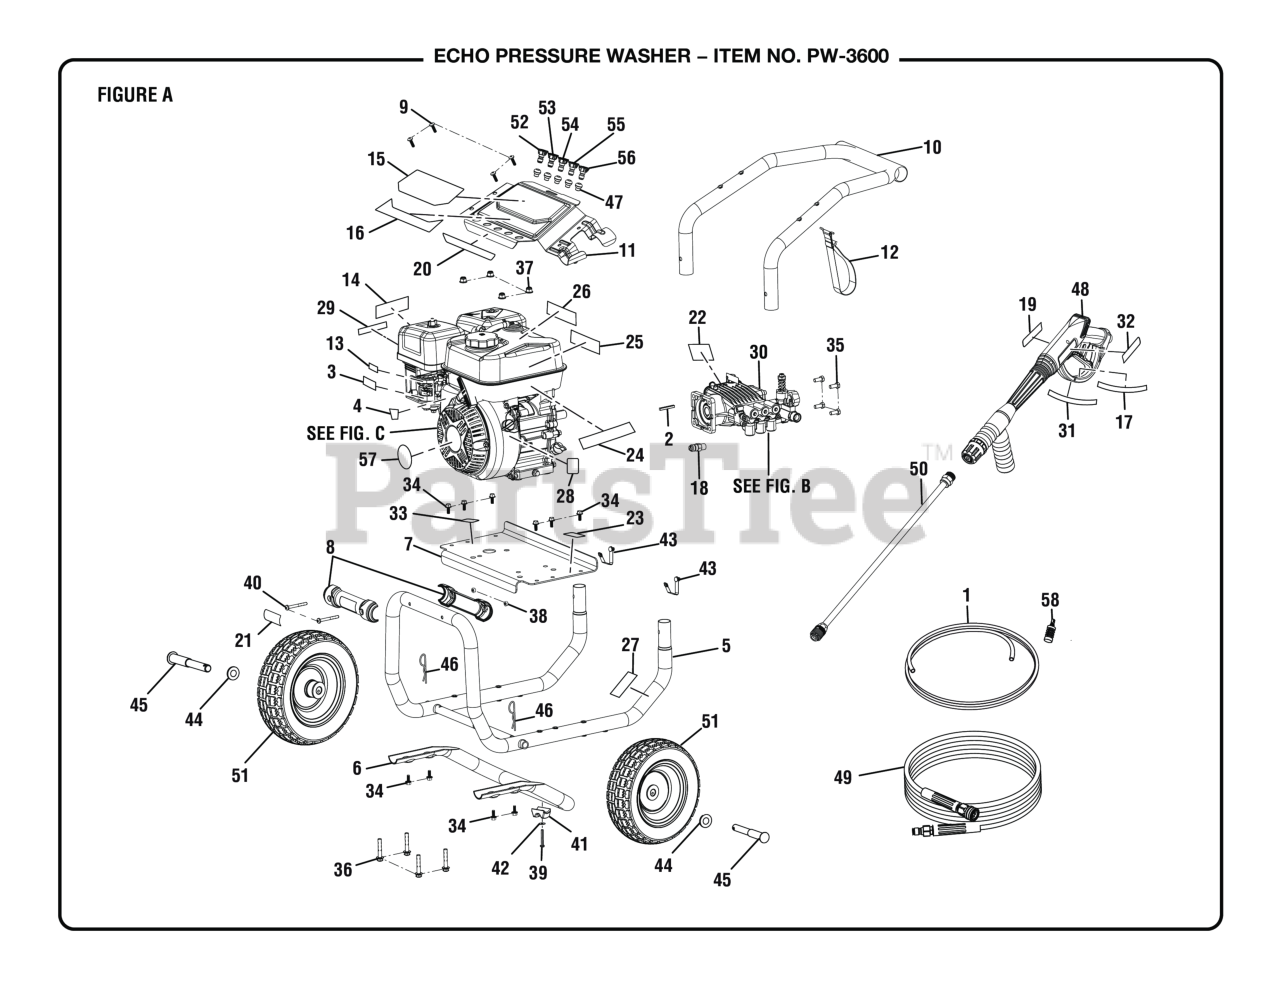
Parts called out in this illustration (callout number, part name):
1	HOSE, SIPHON
3	LABEL, FUEL VALVE
4	LABEL, CHOKE/FUEL CALLOUT
5	FRAME, MAIN
6	FRAME, REAR
7	PLATE, ENGINE
8	GRIP, FRONT HANDLE
9	SCREW, PHILLIPS HEAD
10	FRAME, HANDLE
12	PLATE, CHAIN GUARD
13	LABEL, CHOKE
14	LABEL, HOT SURFACE
15	LABEL, LOGO
16	LABEL, PERFORMANCE
17	LABEL, TRIG HNDL(FR/SP)
18	VALVE, THERMAL RELEASE
19	LABEL, TRIGGER HANDLE LOGO
20	LABEL, NOZZLE
21	LABEL, FRONT GRIP LOGO
22	LABEL, PUMP LOGO
23	LABEL, LOW OIL SHUTDOWN
24	LABEL, COMBUSTION WARNING
25	LABEL, DANGER
26	LABEL, E85
27	LABEL, INQUIRIES
28	LABEL, ENGINE SWITCH
29	LABEL, EMC
30	PUMP, PW-3600
31	LABEL, TRIGGER HANDLE RATING
32	LABEL, TRIG HNDL (ENG)
33	LABEL, DATA WARNINGS
34	BOLT, FLANGE
35	BOLT, HEX HEAD
36	BOLT, FLANGE HEAD
37	NUT, NYLOC FLANGE
38	NUT, NYLOC
39	SCREW, TORX PAN HEAD
41	RUBBER FOOT
43	CLIP, HANDLE SPRING
46	PIN, HITCH
47	GROMMETS
48	CATCHER, CHAIN
49	HOSE, HIGH PRESSURE (BRAIDED)
50	WAND, SPRAY
52	NOZZLE, 0 DEGREE
53	NOZZLE, 15 DEGREE
54	NOZZLE, 25 DEGREE
55	NOZZLE, 40 DEGREE
56	NOZZLE, SOAP
57	LABEL, RECOIL
58	PREFILTER
